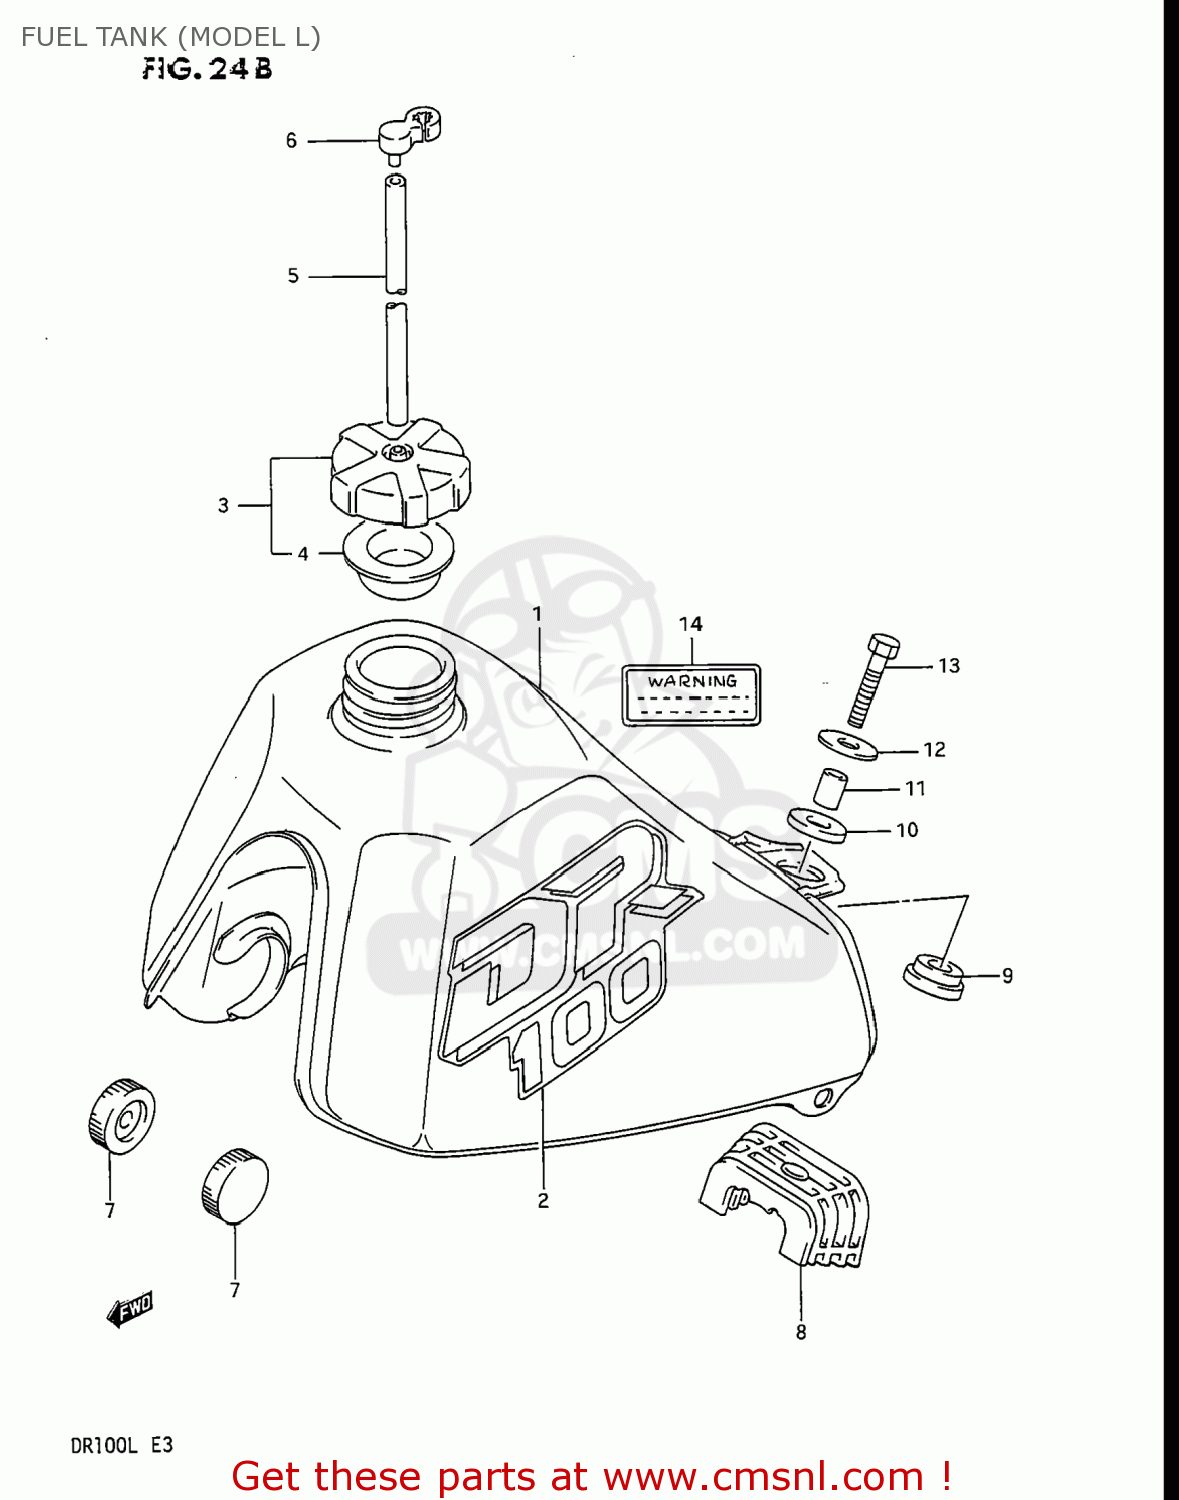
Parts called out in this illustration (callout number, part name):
1	TANK ASSEMBLY,FUEL
2	EMBLEM SET,FUEL TANK
3	CAP SET,FUEL TANK
4	GASKET (NAS)
5	HOSE
6	CLAMP,FUEL TANK BREATHER HOSE
7	CUSHION
8	CUSHION,FUEL TANK
9	CUSHION
10	CUSHION
11	SPACER(8.5X12X19)
12	WASHER (8.5X29X1.6)
13	BOLT
14	LABEL (WARNING)
